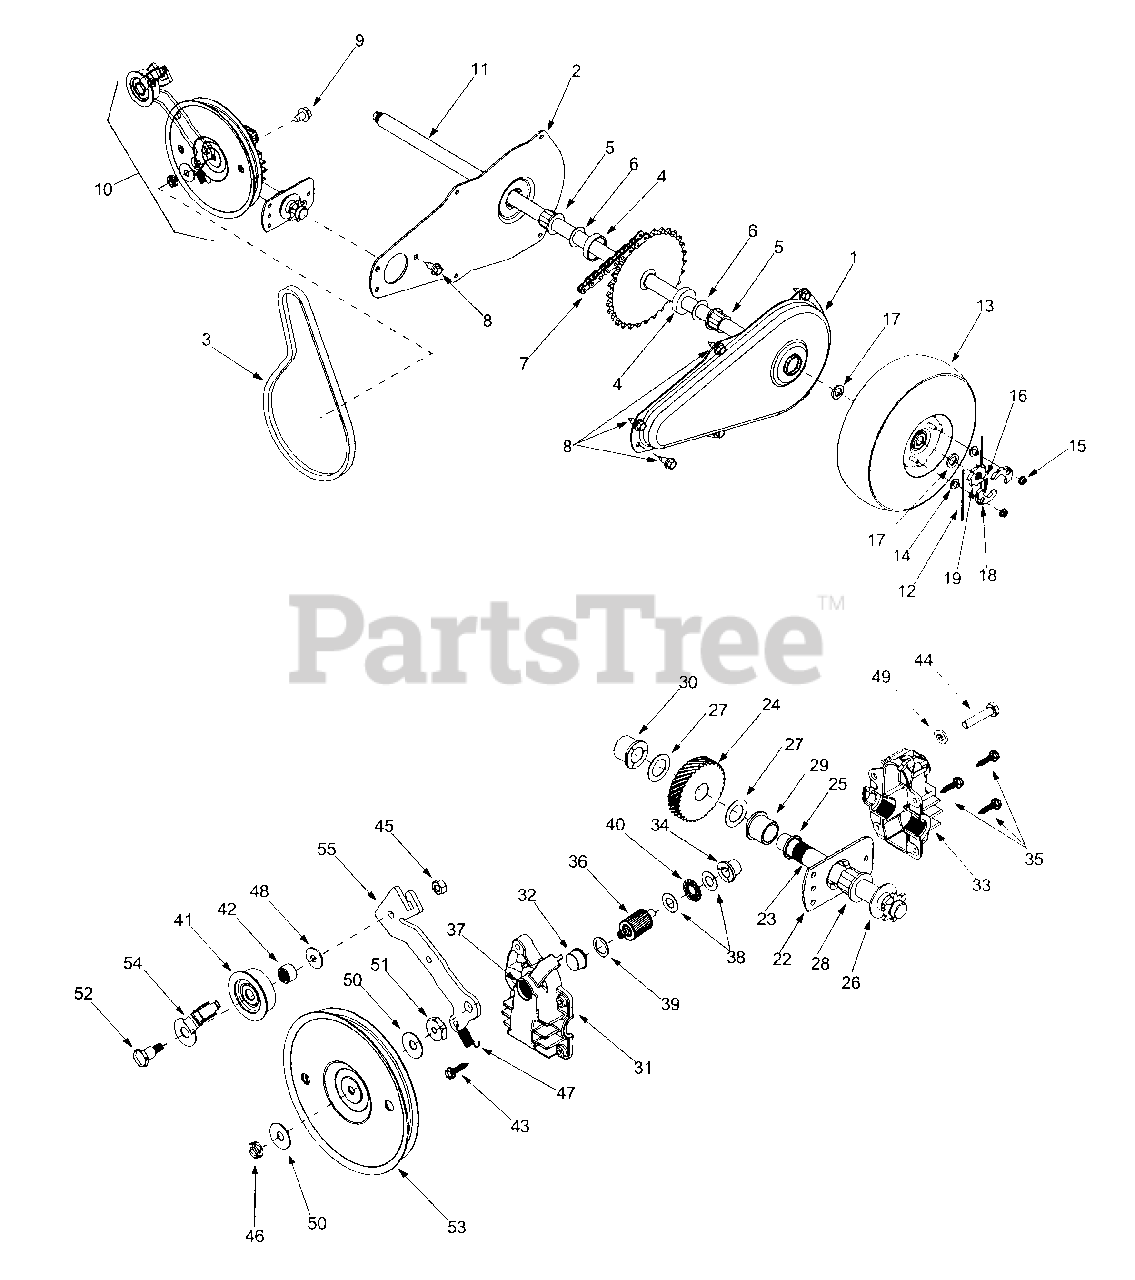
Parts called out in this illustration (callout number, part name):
3	V-Belt
4	Spacer
5	Hex Flange Bearing
6	Flat Washer
7	Chain
8	Hex Washer Screw 1/4-14
9	Hex Washer Screw 5/16
10	Transmission Assembly
11	Axle Assembly
12	Plastic Spring Ratchet
13	Wheel Complete 10 x 4 x 4
14	Hex Nut 1/4-20
15	Hex Flanged Lock Nut 1/4-20
16	Cotter Pin
17	Flat Washer 5/8 ID x 1.0 OD
18	Pawl LH .345 ID
18	Pawl RH .345 ID
19	Wheel Ratchet 1.62 OD x .5 serr
21	Transmission Assembly Complete
22	Hex Bearing Cup
23	Output Shaft 6T Sprocket
24	Helical 34T Gear
25	Oil Seal
26	Flat Washer.64 ID x 1.24 OD
27	Flat Washer 5/8 x 1.0
28	Hex Flange Bearing .631 ID
29	Flange Bearing .629 ID
30	Flange Bearing .566 ID
31	Lower Housing
32	Flange Bearing .503 ID
33	Upper Housing
34	Flange Bearing .378 ID
35	Hex Washer Screw #10-16 x .75
36	Pinion Shaft 10T
37	Oil Seal
38	Thrust Washer .382 ID x .684 OD
39	Flat Washer .504 ID x .70 OD
40	Thrust Bearing .375 ID x .812 OD
41	Pulley Ass'y Idler w/ Bearing
42	Needle Bearing .375 ID x .375 OD
43	Hex Screw #10-16 x .75
44	Hex Cap Screw 1/4-20 x 1.25
45	Hex Nut 1/4-28
46	Hex Jam Nut 5/16-24 LH Thd
47	Extension Spring 1.12 Lg
48	Bell Washer .265 ID x .75 OD
49	Lock Washer 1/4
50	Bell Washer .325 ID x .930 OD
51	Shoulder Spacer .375 ID x .165 OD
52	Shoulder Bolt 1/4-28 x .375
53	Flat Pulley 5.06 Dia
54	Belt Keeper
55	Idler Bracket
